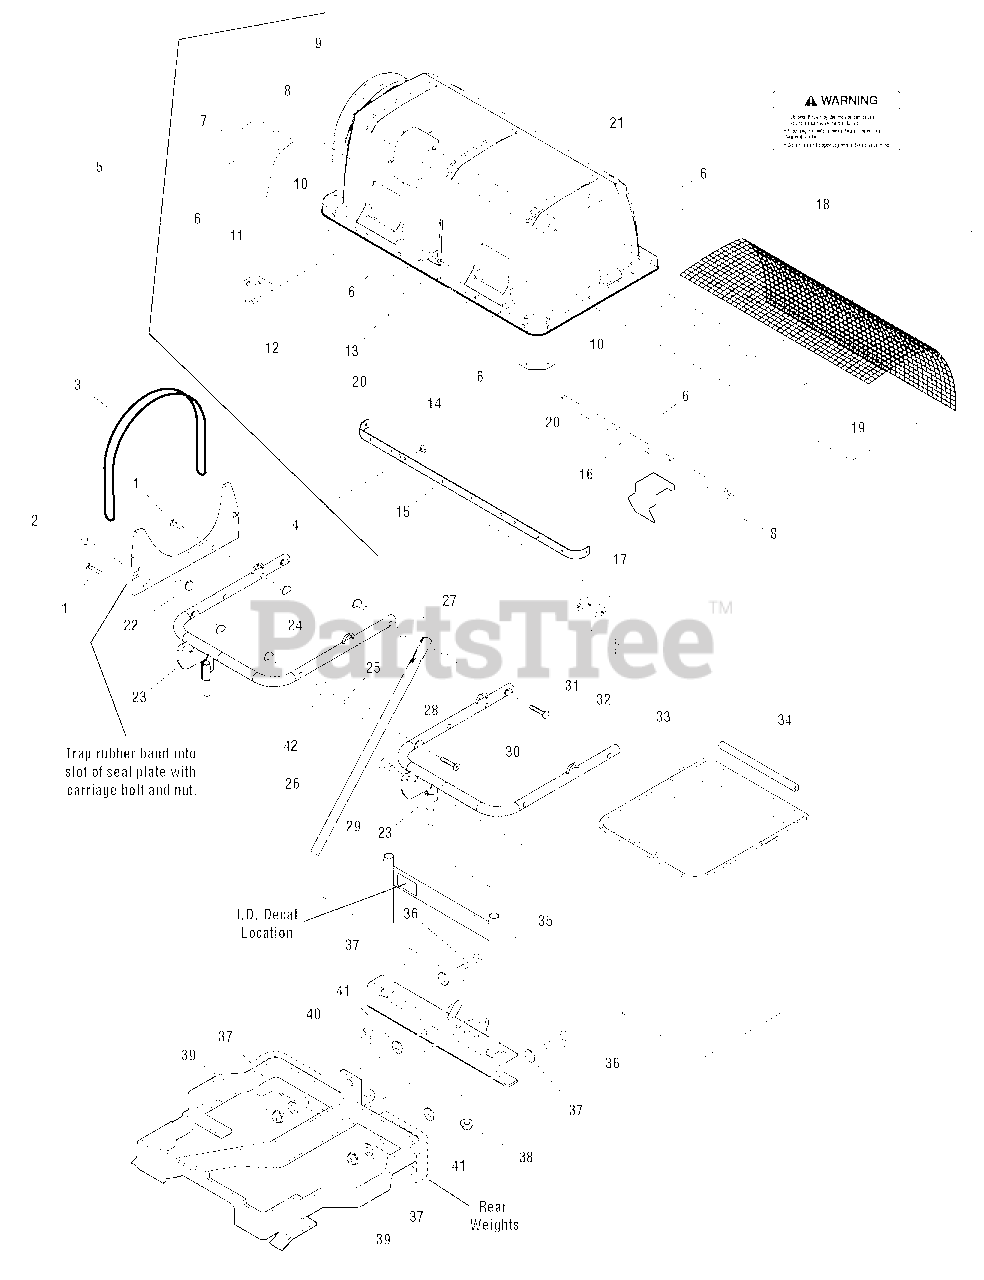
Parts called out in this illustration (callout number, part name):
1	CAPSCREW, Hex Flange Whiz Lock Dog Point, 5/16-18 x 1
2	CARRIAGE BOLT, 5/16-18 x 5/8 G5
3	STRAP, Black Rubber
4	PLATE, Hopper Elbow Seal
5	HOPPER TOP ASSEMBLY,
6	RIVET, Pop
7	WINDOW, Clear PVC
8	WASHER, 3/16
9	TOP, Hopper Black Plastic
10	SEAL, Corner, Black Rubber
11	HINGE, Hopper Top
12	CAPSCREW, Hex Flange Whiz Lock, 1/4-20 x 3/4
13	SEAL, Center, Black Rubber
14	NUT, Hex Flange, 1/4-20 ESNA
15	STIFFENER, Front Hopper
16	STIFFENER, Rear, 24-13/16 Long
17	LATCH, Hopper
18	SCREEN, 1/4 Mesh, 20 x 28
19	RETAINER, Screen, Nylon Push In Type
20	WASHER, 3/16 x 3/4
21	DECAL, Warning Objects Thrown by Mower
22	NUT, Hex Flange, 5/16-18 ESNA
23	PIPE & SHAFT ASSEMBLY, Support Grass Catcher
24	NUT, Pipe 5/16-18
25	SPACER, 5/16
26	BRACE, Tube Center
27	WASHER, 5/16
29	PIN, Round Head Drilled, 1/2 x 1
30	SCREW, Hex Flat Head, 5/16-18 x 2
31	WASHER, 1/2
32	CLIP, Hair Pin Spring Wire, 1-5/8
33	BAG & RIM ASSEMBLY, Grass Catcher
34	EDGING, 13-1/8 Long, PVC Tube White
35	HITCH ASSEMBLY, Grass Catcher
36	CAPSCREW, Hex Head, 3/8-16 x 1-3/8 G5
36	CAPSCREW, Hex Head, 3/8-16 x 2 G5
37	WASHER, 3/8
38	NUT, Hex Flange Two-Way Lock, 1/2-13
39	NUT, Hex Flange, 3/8-16 ESNA
40	CAPSCREW, Hex Head, 1/2-13 x 1-1/4 G5
41	WASHER, Flat
42	WASHER, Flat, 5/16
